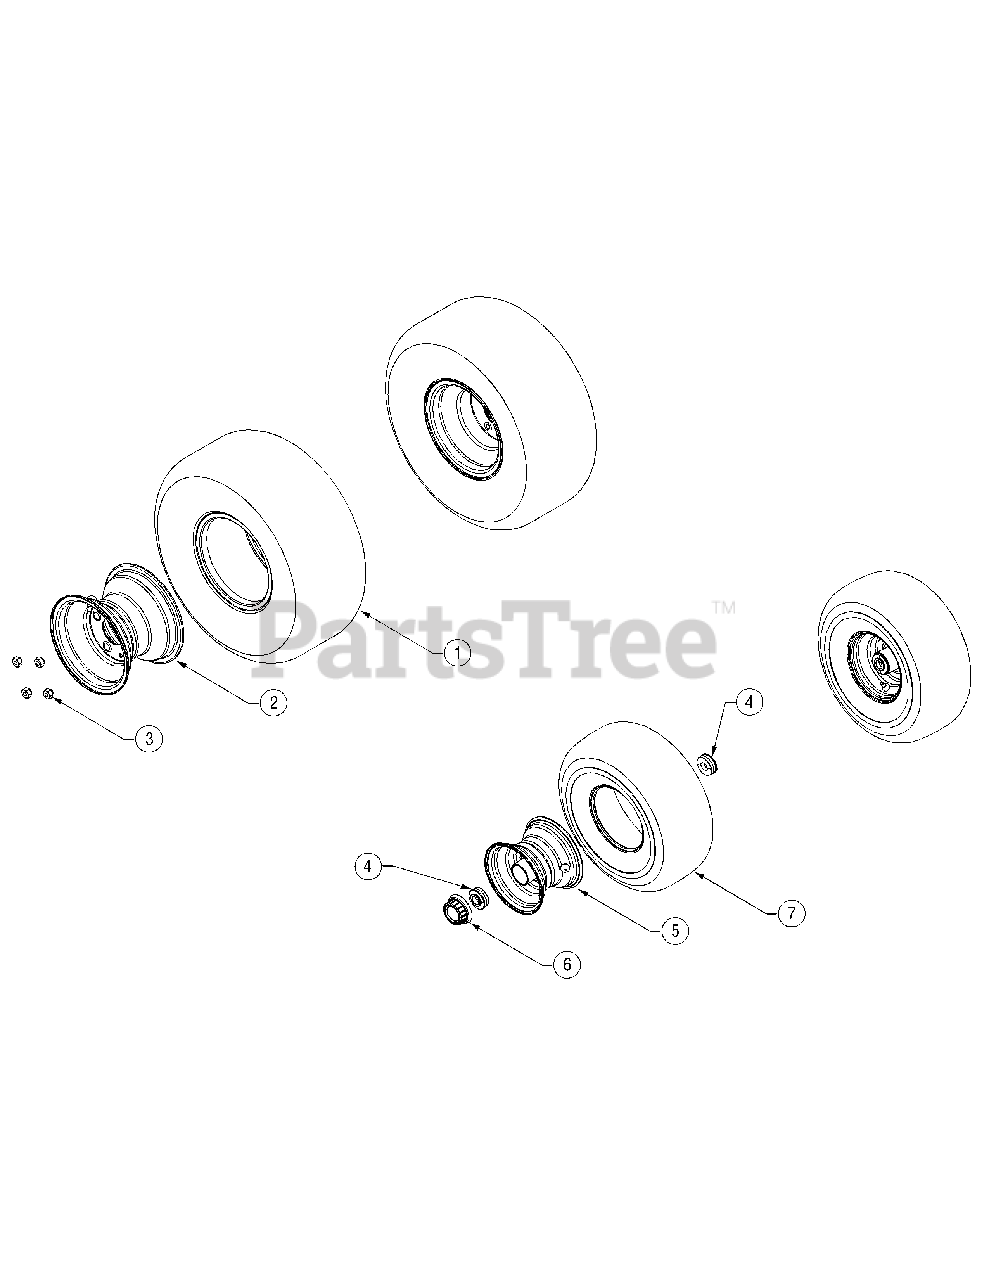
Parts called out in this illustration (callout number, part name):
1	Turf Tire, Cub Cadet 23 x 9.5 x 12
3	Lug Nut, 7/16-14
4	Bearing, Ball,.75 ID x 1.75 OD
6	Hub Cap
